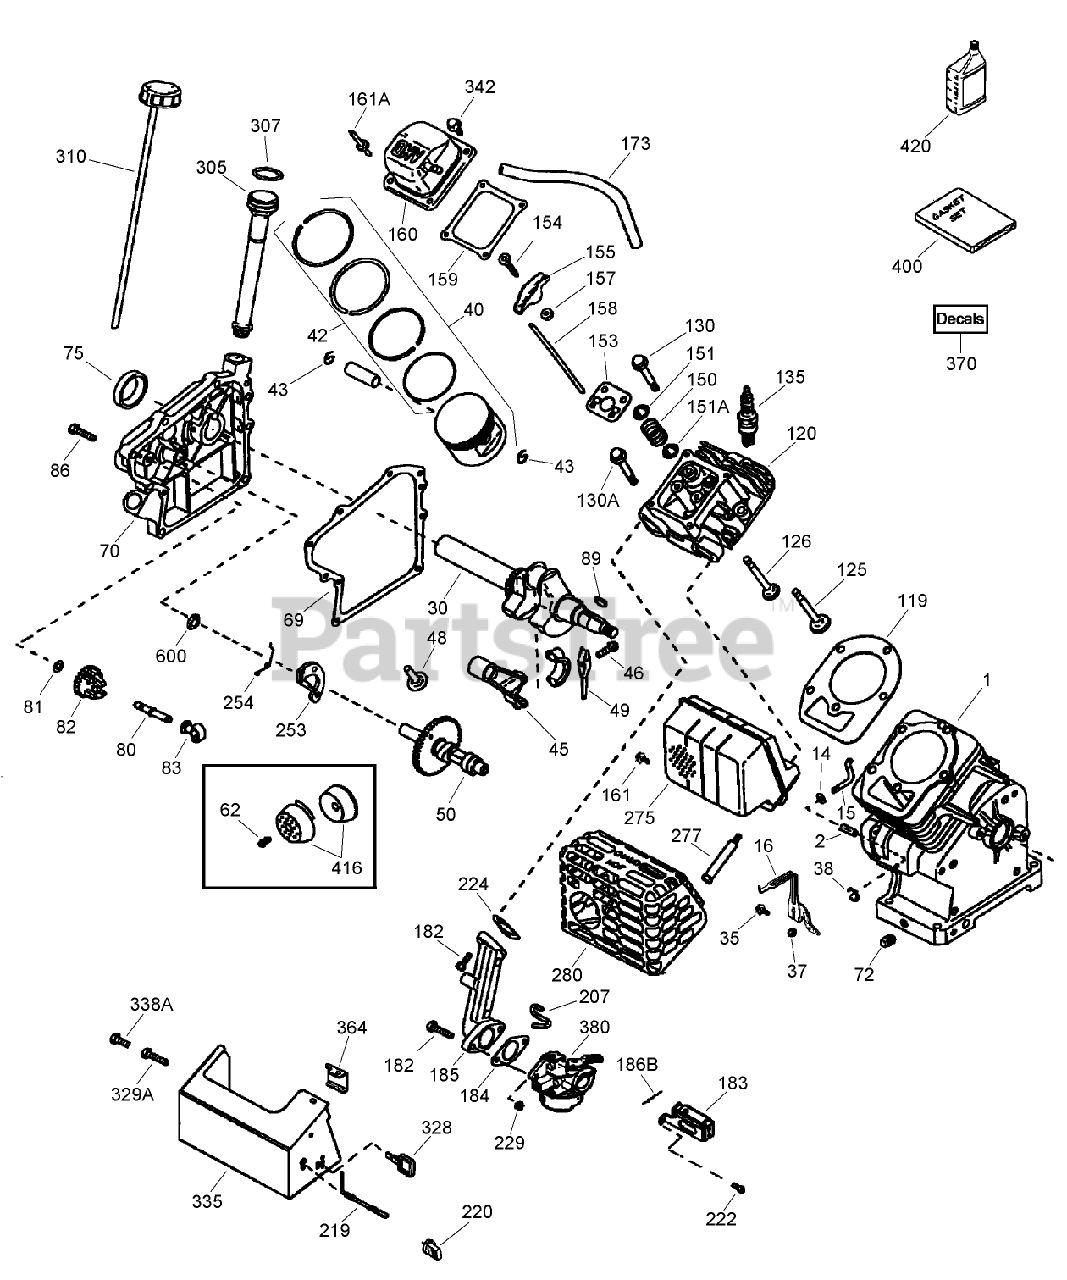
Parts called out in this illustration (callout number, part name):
1	Cylinder ASM (Includes 2, 20, 72, 72A)
2	Pin-Dowel
14	Washer
15	Rod-Governor (Includes 38)
16	Lever-Governor
30	Crankshaft ASM
35	Screw (T-25, 10-32 X 63/64)
37	Nut-Square
38	Ring-Retaining
40	Piston, Pin and Ring Set (.010 O S)
40	Piston, Pin and Ring Set (STD)
42	FITTING - TANK 1"
42	FITTING - TANK 3/4"
43	Ring-Retaining, Piston Pin
45	Connecting Rod Assembly (Incl. Ref. #46 49)
46	Bolt-Rod, Connecting
48	Lifter-Valve
49	Dipper-Oil
50	Camshaft
62	Screw (8-32 x 3/8)
69	Gasket-Cover, Cylinder
70	Cover-Cylinder (Includes 75 -83, 311)
72	Plug-Drain, Oil (SQH 1/4-18)
75	Seal-Oil
80	Shaft-Governor
81	Washer-Flat
82	Governor Gear ASM
83	Spool-Governor
86	Screw (1/4-20 x 1-1/4)
89	Key-Flywheel
119	Gasket-Head, Cylinder
120	Head-Cylinder (Includes 151A)
125	Valve-Exhaust (1/32 O S)
125	Exhaust Valve (Std.)(Incl. 151)
126	Valve-Intake (STD) (Includes 151, 151A)
130	Screw (5/16-18 x 1-1/2)
130A	Screw (5/16-18 x 2-41/64)
135	Spark Plug-Resistor (R N 4C)
150	Spring-Valve
151	Cap-Valve, Spring
151A	Seal-Valve, Intake
153	Guide-Rod, Push
154	Stud-Arm, Rocker
155	Arm-Rocker
157	Nut (1/4-28)
158	Rod-Push
159	Gasket-Cover, Rocker Arm
160	Cover-Arm, Rocker
161	Screw (1/4-20 x 19/32)
161A	Stud
173	Tube-Breather
182	Screw (1/4-20 x 1)
183	Bracket-Choke
184	Gasket
185	Pipe-Intake
186B	Spring-Choke
207	Link-Throttle
219	Rod-Choke
220	Knob-Control
222	Screw (10-32 x 1/2)
224	Gasket-Pipe, Intake
229	Nut (1/4-20)
253	Weight-Release, Compression
254	Spring-Release, Compression
275	Muffler (Carburetor Side Discharge)
277	Screw (1/4-20 x 2-9/32)
280	Shield-Heat
305	Tube-Fill, Oil
307	O-Ring
310	Dipstick
328	Key-Ignition
329A	Screw (8-32 x 23/64)
335	Cover-Carburetor
338A	Screw (10-32 x 3/8)
342	Screw (1/4-20 x 31/64)
364	Bracket-Cover, Carburetor
370	Decal-Tecumseh Logo for Top of Recoil Starter
370	Instruction Decal-Caution, read owner manual
370	Decal-Primer, International Symbol
370	Decal-Warning (Bilingual)
370	Decal-Hot Surfaces
370	Decal-Start Button, Electric
370	Decal - Speed Control, Choke and Key
380	Carburetor ASM (Includes 184)
400	Gasket Set
416	Spark Arrestor Kit (Incl. 417)(Optional)
420	Oil-Engine, S A E 5W30
600	Washer
700	Engine Replacement
701	Short Block Replacement
999	Winter Maintenance Kit (Includes 0W30 Synthetic Oil)
999	Winter Maintenance Kit (S A E 5W30 Oil)
